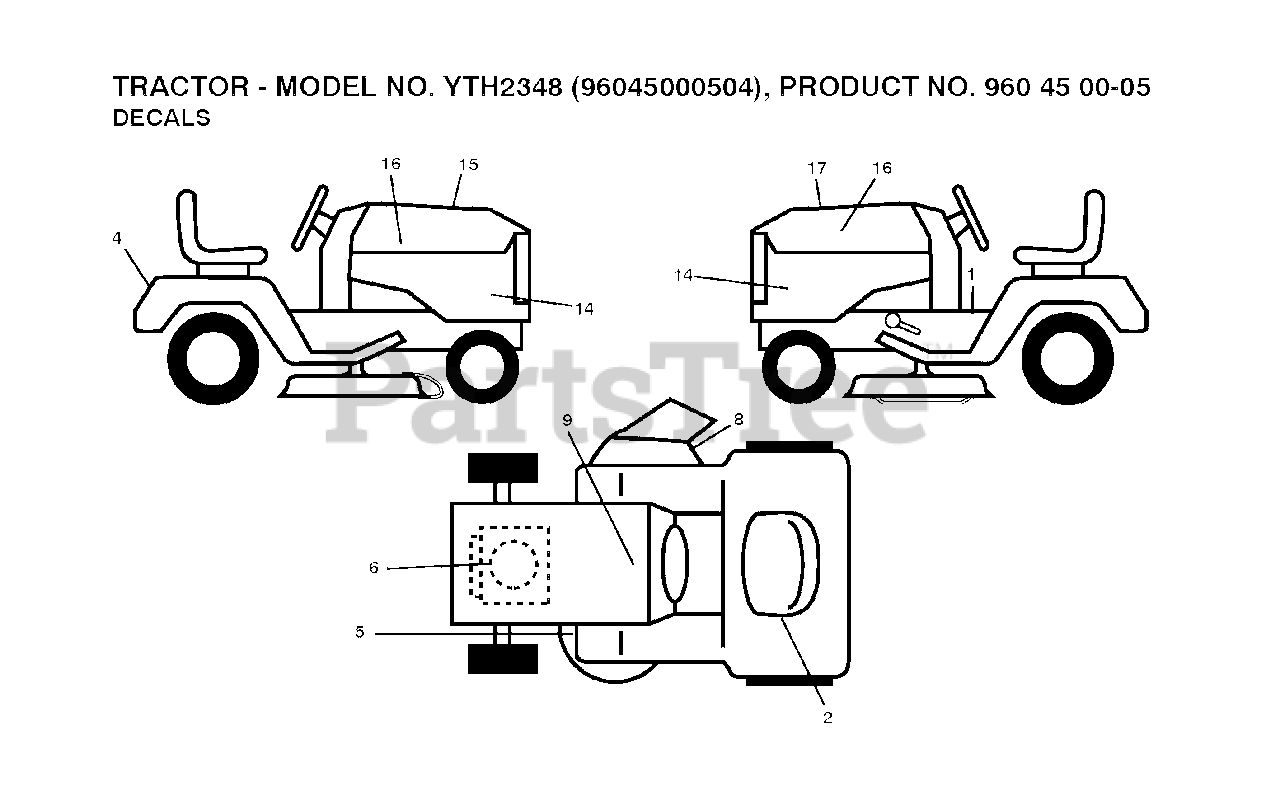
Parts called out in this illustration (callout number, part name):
1	DECAL.WARN.START.INSTRUCTIONS
2	DECAL,ETHANOL E85 WARNING
4	DECAL.FENDER
5	DECAL.MOWER
6	Decal, Engine Hp
8	DECAL.MOWER.SCH.48/54
9	DECAL BTRY SYMBOLS
14	DECAL, PANEL SIDE
15	DECAL HOOD CUST. RESP.
16	DECAL.HOOD.LOGO.ORANGE.HUSQVAR
